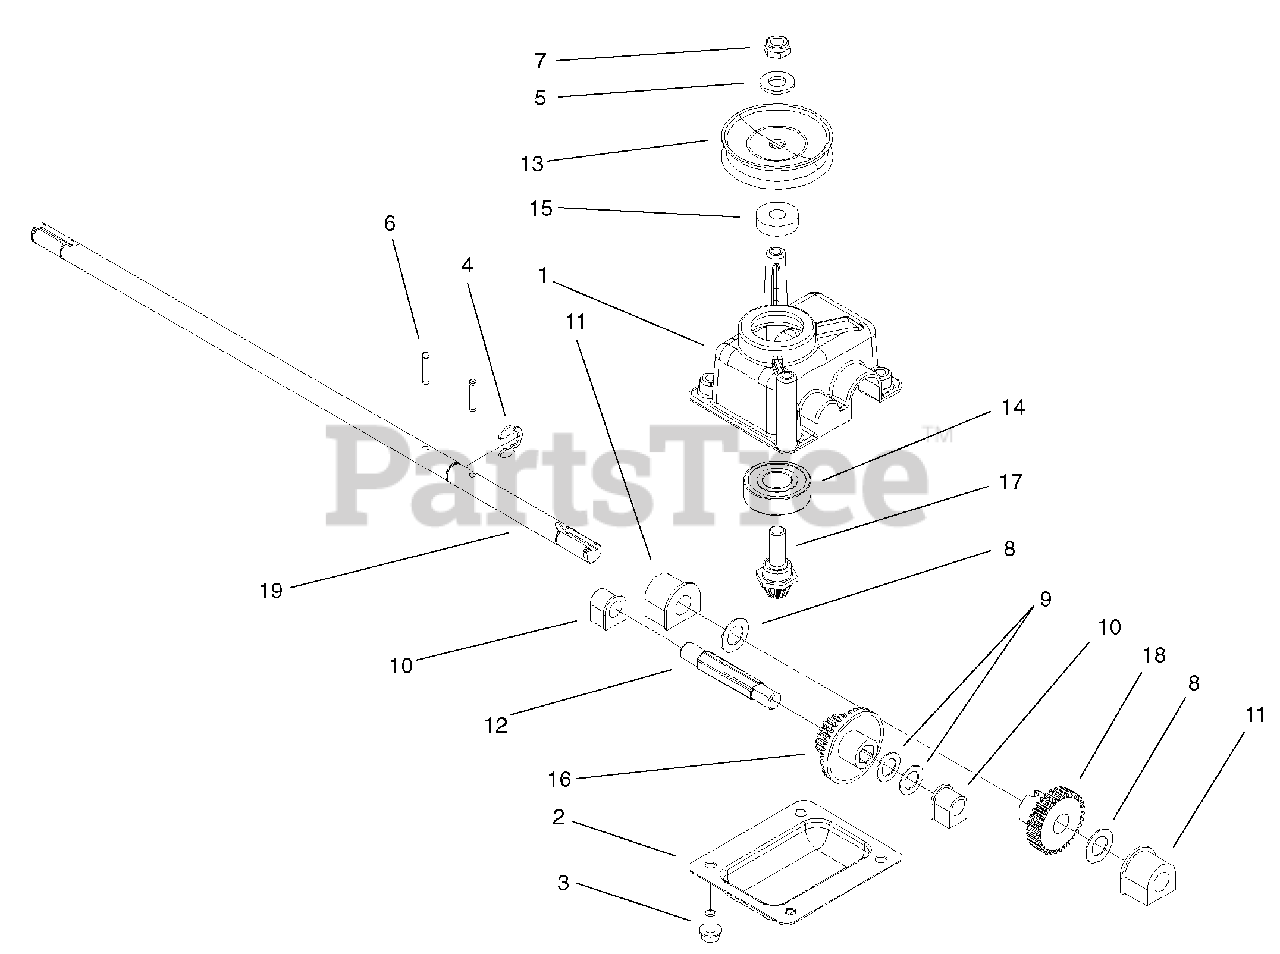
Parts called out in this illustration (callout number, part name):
1	Casting-Case, Gear
2	Cover-Case, Gear
3	Screw-HWH
4	Ring-Retaining
5	Washer-Flat
6	Pin-Groove
7	Nut-Lock NI
9	Washer-Thrust
11	Bushing-Output
12	Shaft-Intermediate
13	Pulley-Half
14	Bearing-Ball
16	Gear-15t Spur,37t Bevel
17	Gear-Pinion, Bevel
19	Shaft-Output
